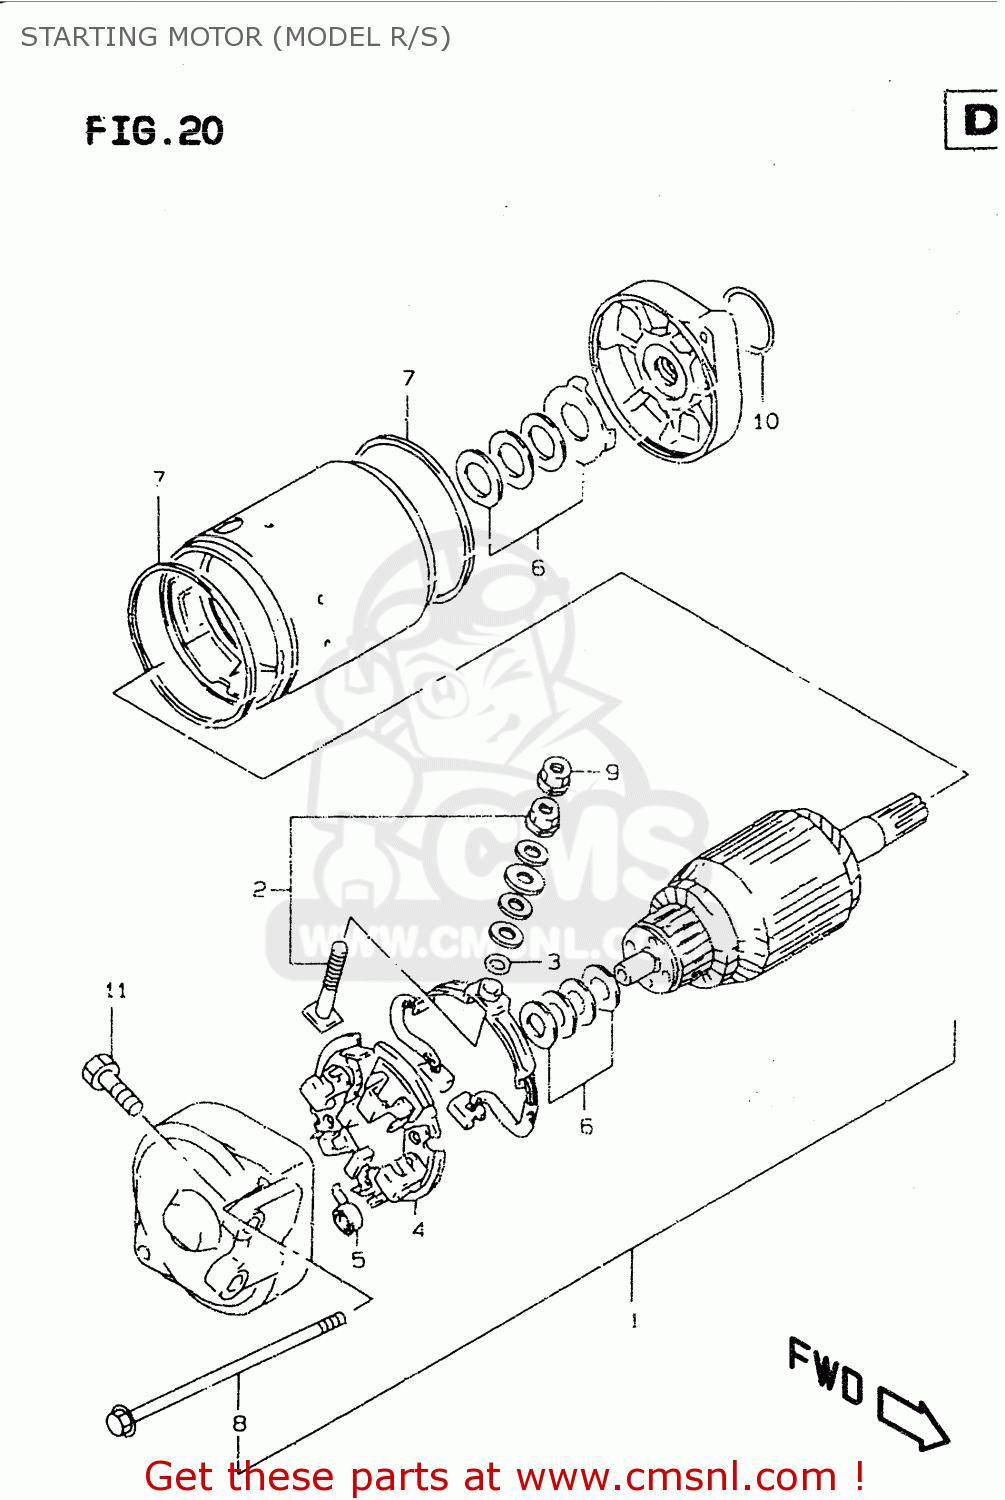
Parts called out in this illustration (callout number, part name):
1	MOTOR ASSY,STARTING
2	TERMINAL SET,BRUSH
3	O RING
4	HOLDER SET,BRUSH
5	SPRING,BRUSH
6	SHIM SET,STARTING MOTOR
7	SQUARE RING
8	BOLT
9	NUT
10	O RING(D:3,ID:24.5)
11	BOLT,CRKCASE,R
